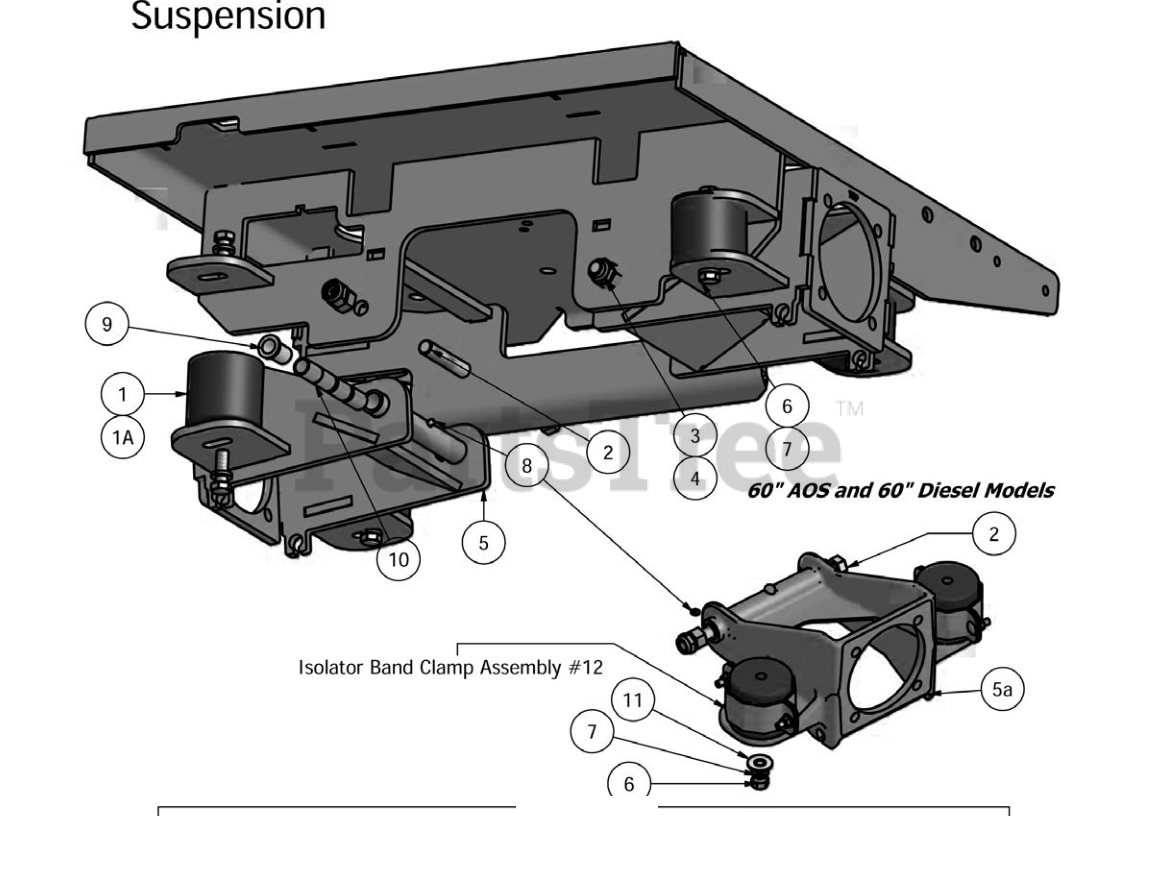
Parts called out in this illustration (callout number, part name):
1	Vibration Mount-Green Dot (60" Only)
1A	Vibration Mount-Blue Dot (72" AOS and All Diesel)
2	5/8"x10" Hex Bolt (Grade8)
3	5/8" Nylock (1/2 Jam)
5	72" Inner Suspension Cage
5A	60" Inner Suspension Cage
6	1/2" x 1 1/2" Hex Bolt
7	1/2" Lock Washer
8	Grease Fitting
9	Shoulder Spacer
10	3/4" Brass Bushing
11	1/2" Flat Washer Gr 8
12	Isolator Band Clamp (35HP Diesel Only)
